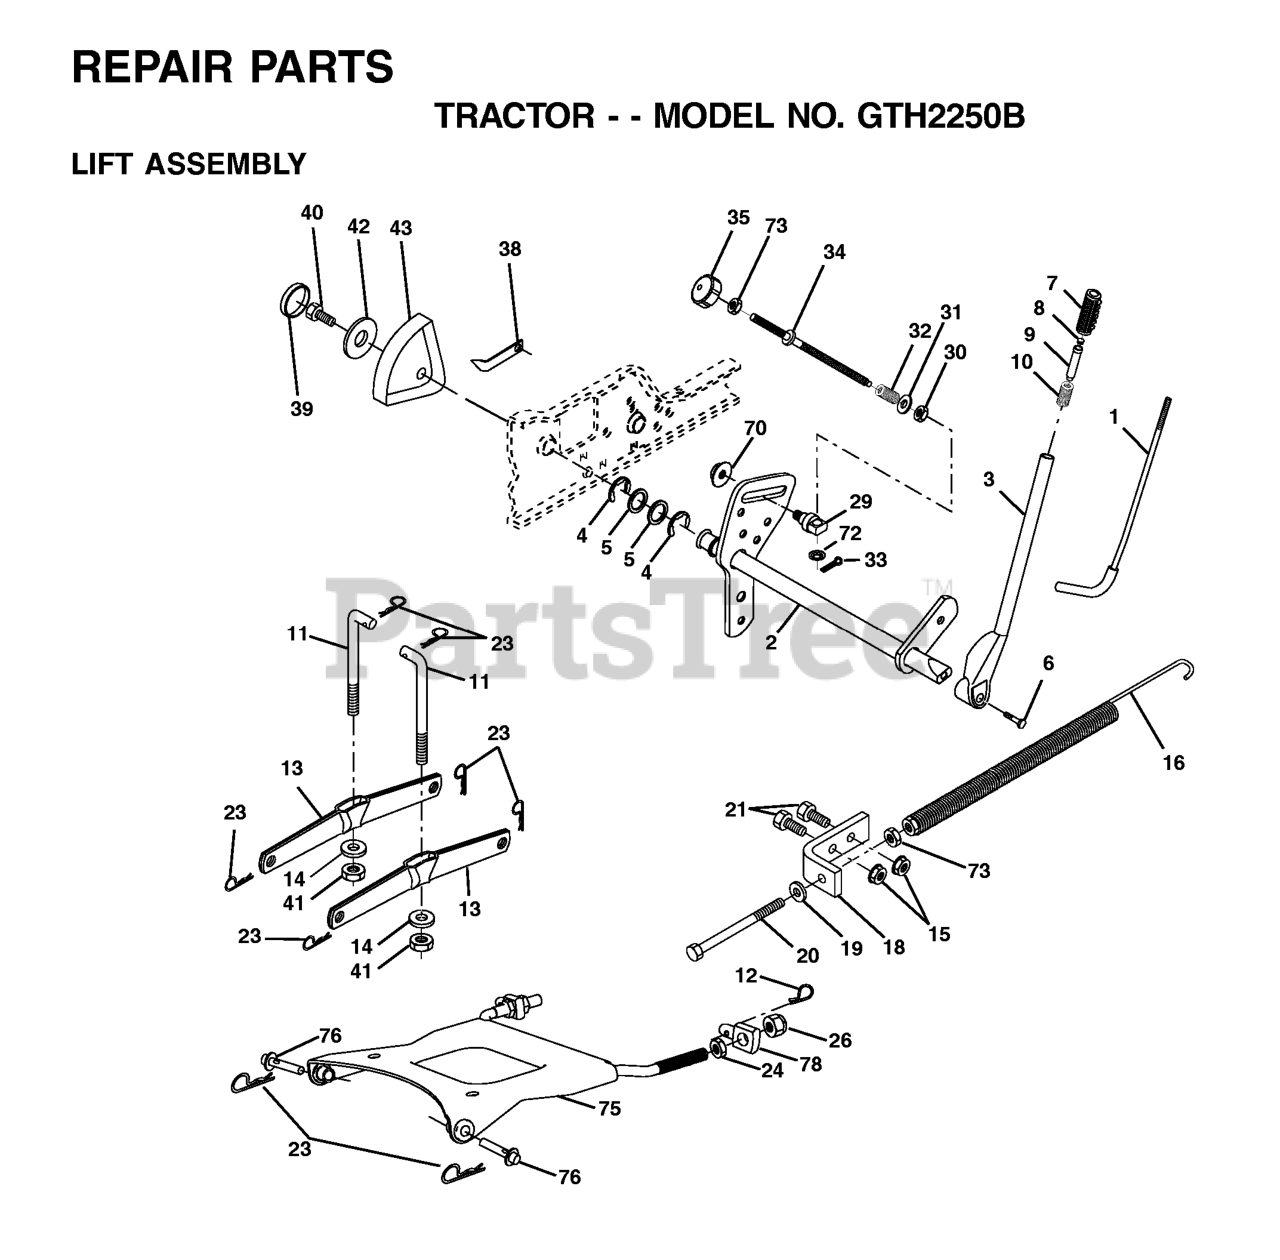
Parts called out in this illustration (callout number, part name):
1	LEVER ROD LT
3	LEVER ASSY-LIFT RH
5	Washer 29/32 x 1 - 1/4 x 16 Ga.
6	Bolt, Fin Hex 3/8-16 x 1-1/12
7	GRIP HANDLE
8	PLUNGER BUT KIT
9	PLUNGER BUT KIT
10	SPRING**
11	LINK LIFT
12	SPRING RETAINER
13	ARM.REAR.SUSPENSION
14	BEARING.PIVOT.LIFT
16	LIFT SPRING
19	WASHER
21	BOLT
23	RETAINER-SPRNG RB
24	NUT.HEX.JAM.1/2-13
26	NUT.LK.W/WSH.1/2.
32	SPRING.COMP.INF.H
33	COTTER PIN
34	ROD.LIFT.ADJUSTABLE
35	KNOB INF 3/8-16
38	POINTER, HEIGHT INDICATOR(2 2)
40	SCREW 5/16-18X1
41	NUT CROWNLOCK 3/8-24
43	HEIGHT INDICATOR
70	NUT
72	NUT PUSH M
73	NUT
75	PLATE ASM SUSP FRONT
76	PIN.FLANGE
78	TRUNION
